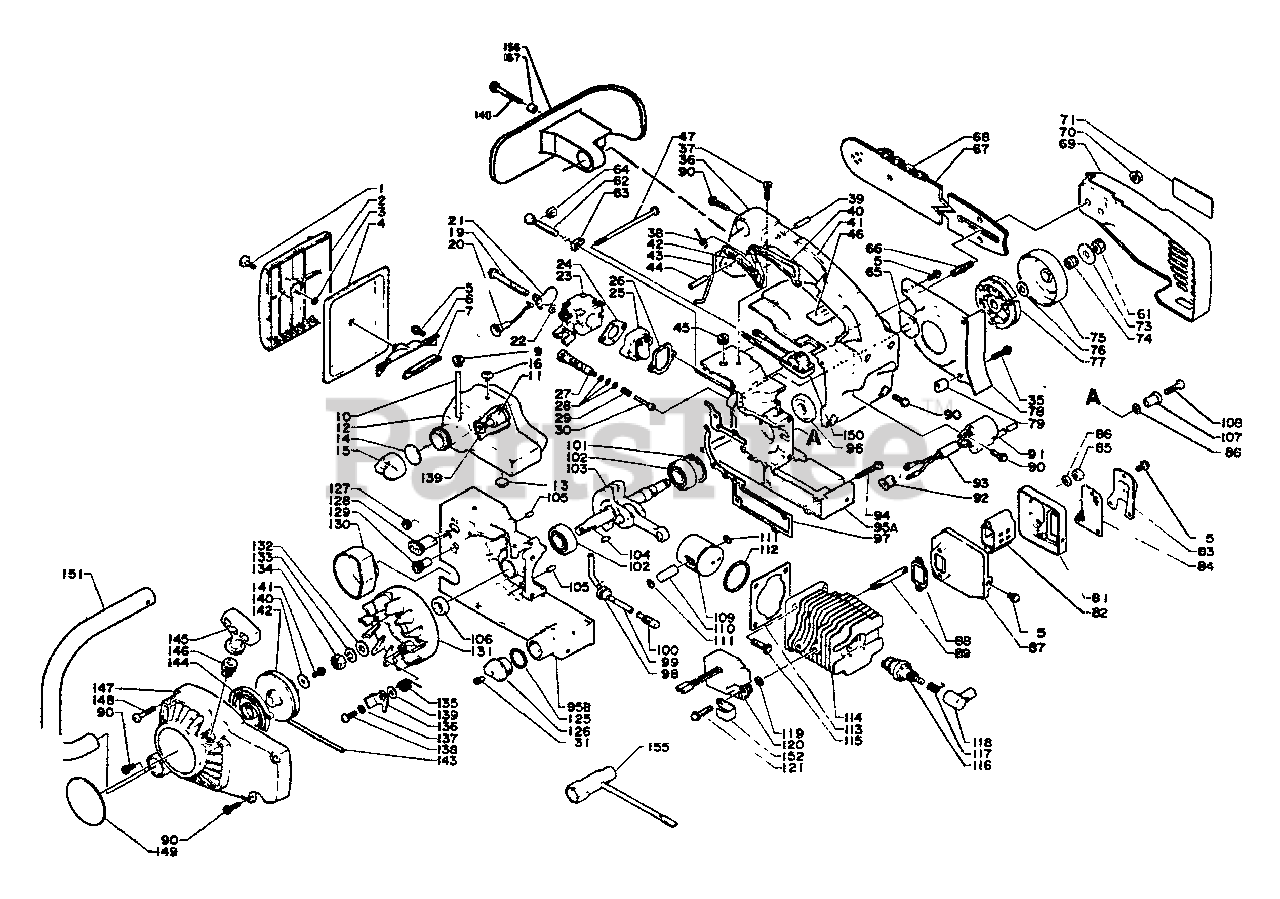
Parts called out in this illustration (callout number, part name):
1	THUMBSCREW
2	COVER, AIR FILTER
3	RING, RETAINING - 3
4	FILTER, AIR
5	SCREW - 4X10
6	BRACKET, AIR CLEANER
7	CUSHION
9	GROMMET
10	FUEL PIPE KIT
11	FILTER, FUEL
12	TANK, FUEL
14	GASKET, CAP
15	CAP
19	SCREW - 5X55
20	ROD, CHOKE
21	SHUTTER, CHOKE
22	WASHER
23	CARBURETOR
24	GASKET, INTAKE
25	INSULATOR
26	GASKET, INTAKE
27	AUTO-OILER ASSY
28	O-RING - 5
31	VENT, TANK
35	SCREW - 4X20
36	HANDLE - TOP
37	SCREW - 4X18
38	SPRING
39	PIN - SPRING -- 5X18
40	LOCKOUT, THROTTLE
41	GRIP, HANDLE
42	TRIGGER, THROTTLE
43	ROD, THROTTLE
44	PIN - SPRING -- 5X25
46	LABEL
61	LOCKNUT - 6
62	SCREW, TENSIONER
63	TENSIONER, CHAIN
65	PLUG
66	STUD, GUIDE BAR
67	GUIDE BAR
68	CHAIN, SAW
69	GUARD, SPROCKET
70	NUT - 6 -- FLANGE
71	LABEL - ECHO
74	BEARING, NEEDLE
75	DRUM, CLUTCH
76	WASHER, CLUTCH
77	CLUTCH ASSY
78	PLATE, SEAL
79	SPACER
81	LID, MUFFLER
82	BAFFLE, MUFFLER
83	GUIDE, EXHAUST
84	SCREEN, SPARK ARRESTOR
85	LOCKNUT - 5
86	WASHER - 5
87	GUIDE, EXHAUST
88	GASKET, EXHAUST
90	SCREW - 4X16
91	COIL, IGNITION
94	SCREW - 4X30
95	CRANKCASE KIT
95A	CRANKCASE KIT
95B	CRANKCASE KIT
96	SEAL, OIL
97	GASKET, CRANKCASE
98	GROMMET
99	PIPE - OIL
100	FILTER, OIL
101	RING, RETAINING - 32
102	BEARING, BALL - 6201
103	CRANKSHAFT ASSY
105	PIN - LOCATING
106	SEAL, OIL
107	CATCHER, CHAIN
108	SCREW - 5X20
109	PISTON
110	PIN, PISTON
111	RING, RETAINING
112	RING, PISTON
113	GASKET, CYLINDER
114	CYLINDER
115	SCREW - 5X20
116	SPARK PLUG -- CJ-8Y
117	SPARK PLUG -- CJ-8Y
118	CAP, SPARK PLUG
119	SPACER
120	COIL, IGNITION
121	SCREW - 5X22
122	PIN, SPLIT -- 2X15
123	WASHER - 2
124	SEAL, FELT
125	O-RING - 16
126	CAP, OIL TANK
128	GROMMET
129	GROMMET
130	SEAL
131	FLYWHEEL
132	WASHER - 8
133	LOCKWASHER - 8
135	SPRING, RETURN
136	PAWL, STARTER
138	SCREW
139	WASHER - 5
139	STARTER ASSY
141	SCREW - 4X10
142	REEL, ROPE
143	ROPE, STARTER - 3X850
144	SPRING, REWIND
145	GRIP, STARTER
146	GUIDE, ROPE
147	CASE, STARTER
148	SCREW - 4X25
149	LABEL - ECHO
150	IGNITION SWITCH ASSY
151	HANDLE - FRONT
152	CLAMP
155	T-WRENCH - 10X19mm
156	GUARD
